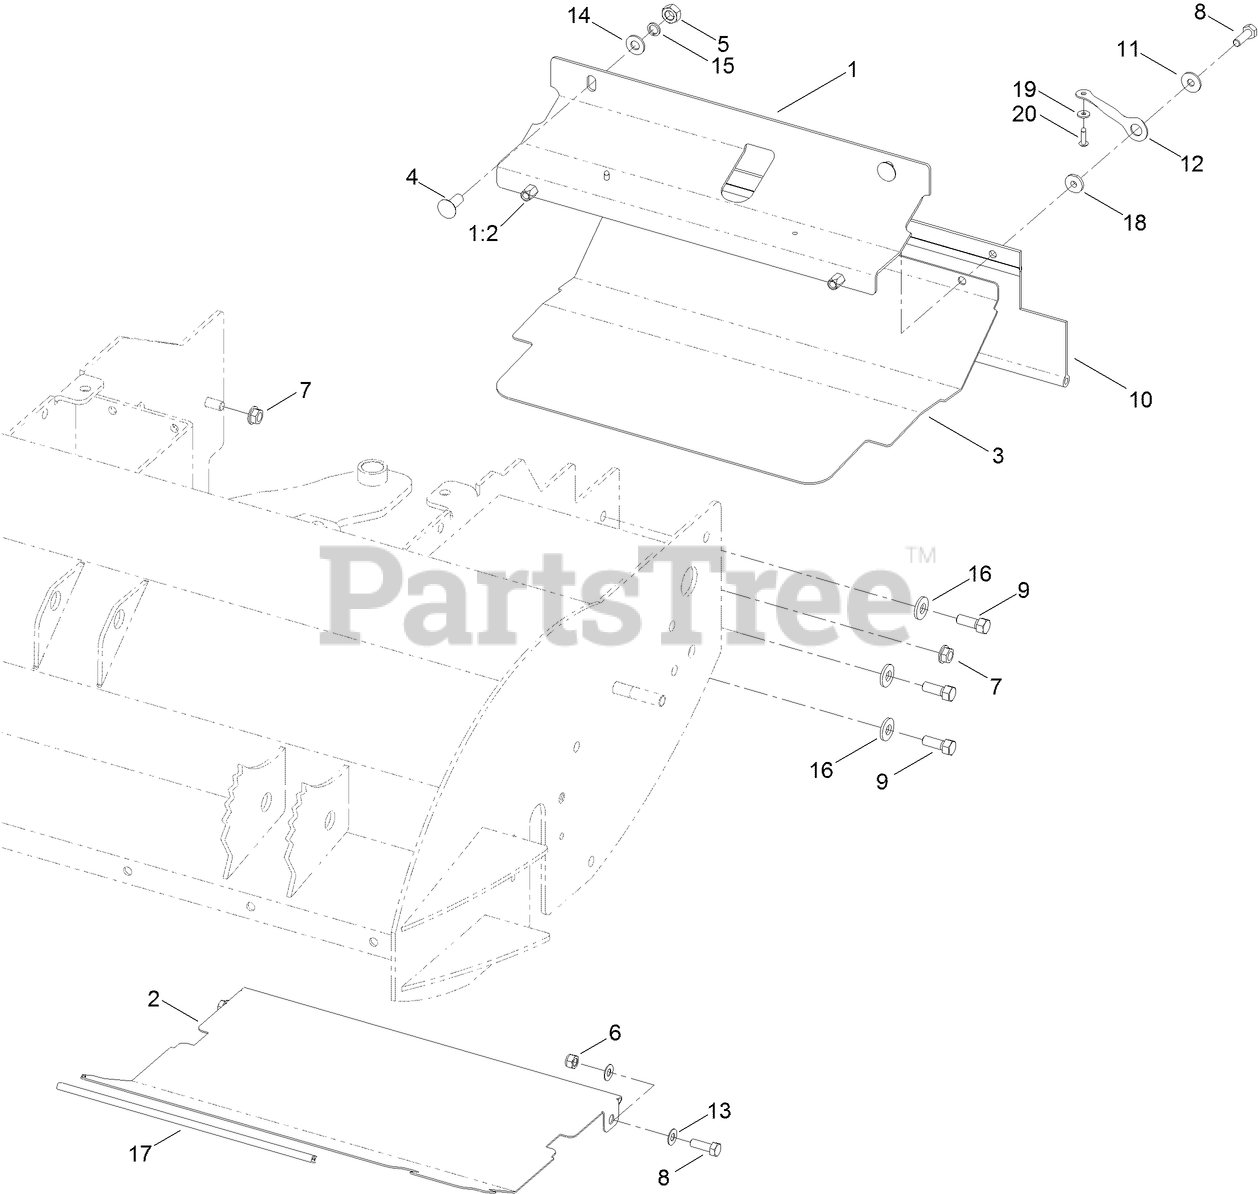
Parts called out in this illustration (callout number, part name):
1	GUARD-DRIVE
1:2	NUT-RIVET
2	GUARD-CENTER DISCHARGE FLAIL
3	GUARD-UNDERSIDE
4	BOLT-CARR
6	NUT-HEX, NI
7	NUT-HHF, WHIZ
8	SCREW-HH
9	SCREW-HH
10	SHIELD-DRAG
11	WASHER
12	LANYARD-3 INCH
13	WASHER
14	WASHER-PLAIN
15	WASHER-LOCK
16	WASHER-BELLEVILLE
17	STRIP-PROTECTION
18	NUT-RETAINER
19	WASHER
20	RIVET
